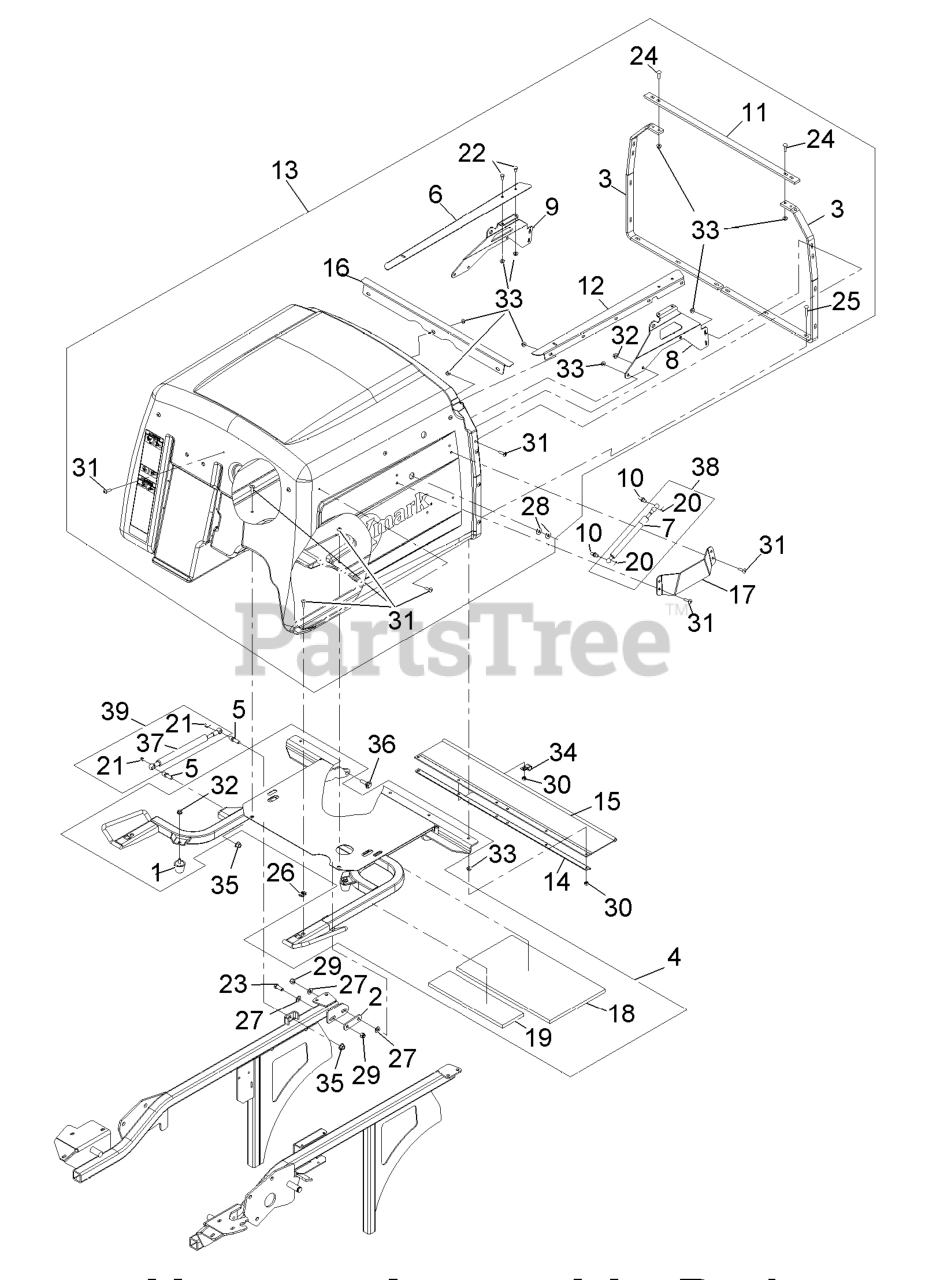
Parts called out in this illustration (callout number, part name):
1	BUMPER-RUBBER
2	ARM-LIFT, DECK
3	REINFORCEMENT-HOPPER
4	HOPPER FRAME ASM
5	STUD-BALL
6	ANGLE-SCREEN TRACK, RH
7	SHOCK-GAS TENSION
8	BRACE-DOOR PIVOT, LH
9	BRACE-DOOR PIVOT, RH
10	STUD-BALL
11	BRACKET-FRAME CONNECT
12	ANGLE-SCREEN TRACK, LH
13	ASM,HOPPER
14	CHANNEL-FRAME, HOPPER
15	DEFLECTOR-GRASS
16	CHANNEL-SCREEN, FRONT
17	PLATE-GUARD
18	INSULATION-FOAM PAD, REAR
19	INSULATION-FOAM PAD, FRON
20	CLIP-RETAINER
21	CLIP-RETAINER
22	SCREW-HH
23	SCREW-HH
24	SCREW-CARR
25	SCREW-CARR
26	Nut-Retainer-Panel 1/4-20
27	WASHER-FLAT
28	WASHER-FLAT
29	NUT-LOCK, NI
30	NUT-LOCK, NI
31	SCREW-TTH
34	CLIP-LOOM
36	SCREW-SHOULDER, HWH
37	SHOCK-COMPRESSION, GAS
38	DAMPER KIT
39	DAMPER KIT
